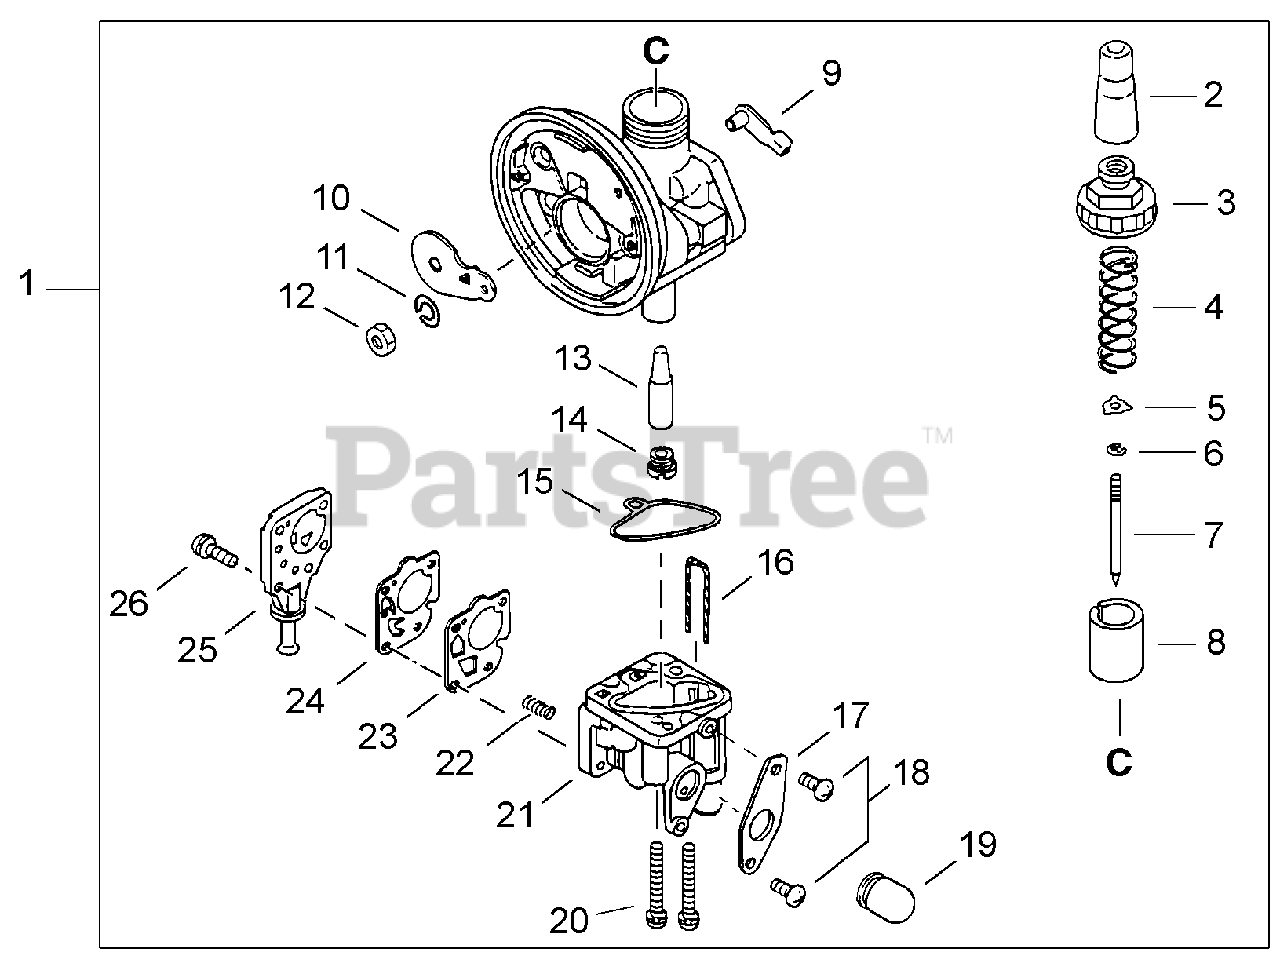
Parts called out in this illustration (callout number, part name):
1	CARBURETOR - K13PR-6E
3	COVER, TOP
4	SPRING, THROTTLE
7	NEEDLE, JET
8	VALVE, THROTTLE
9	LEVER, CHOKE
10	PLATE, CHOKE
11	WASHER, SPRING 6
12	NUT, LOCK
13	NEEDLE, JET
14	JET, MAIN #64
15	GASKET, CHAMBER
16	WIRE, DRAIN
18	SCREW 4×8
20	SCREW 4×30
22	SPRING, COIL
23	GASKET, DIAPHRAGM
24	DIAPHRAGM, FUEL PUMP
25	COVER, PUMP
26	SCREW 3×10
